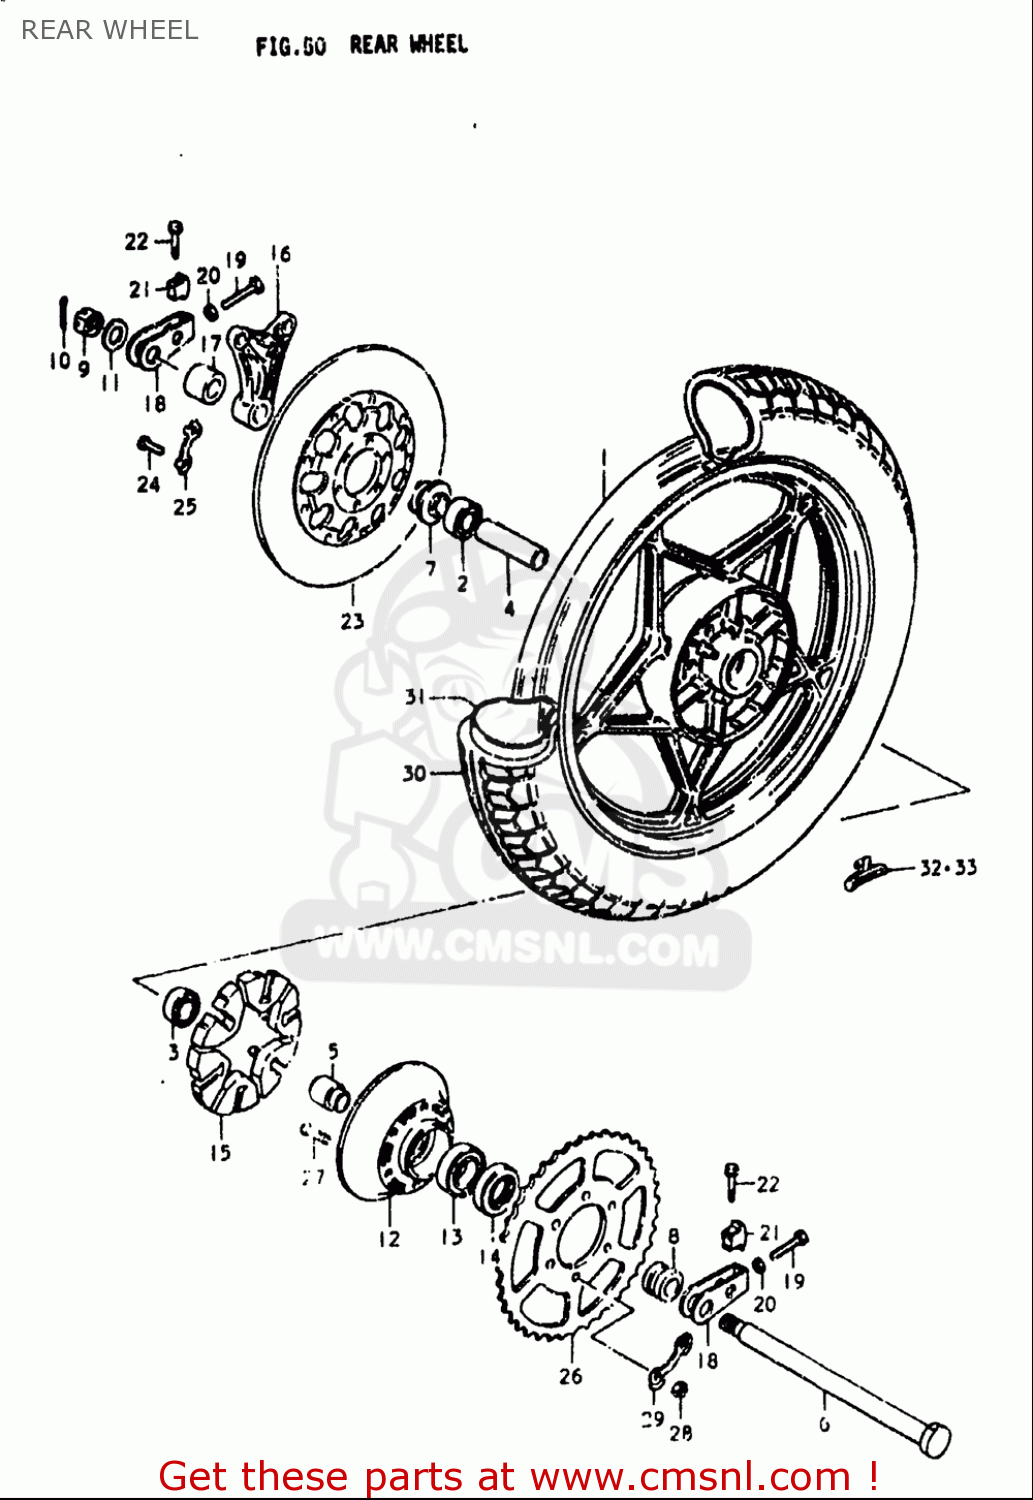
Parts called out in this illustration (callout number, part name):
2	BEARING WHEEL REAR(20X47X14)
3	BEARING(20X47X14)
4	SPACER(20.5X28X88)
5	SPACER,REAR HUB BEARING
7	SPACER,RR AXLE,R
8	SPACER(20X33X28.3)
9	NUT 18MM
10	PIN
11	WASHER(19X34X4)
12	DRUM,RR SPROCKET MOUNTING
13	BEARING(25X62X17)
14	SEAL,OIL(33X62X7)
15	ABSORBER,RR HUB SHOCK
16	BRACKET,RR,CALIPER
18	ADJUSTER,CHAIN
19	BOLT 8X50
20	NUT
21	SUPPORTER,CHAIN ADJUST
22	BOLT
23	DISC,BRAKE
24	BOLT(8X30)
25	WASHER
26	SPROCKET,RR
27	BOLT(10X35.5)
28	NUT
29	WASHER
32	BALANCER,WHEEL
